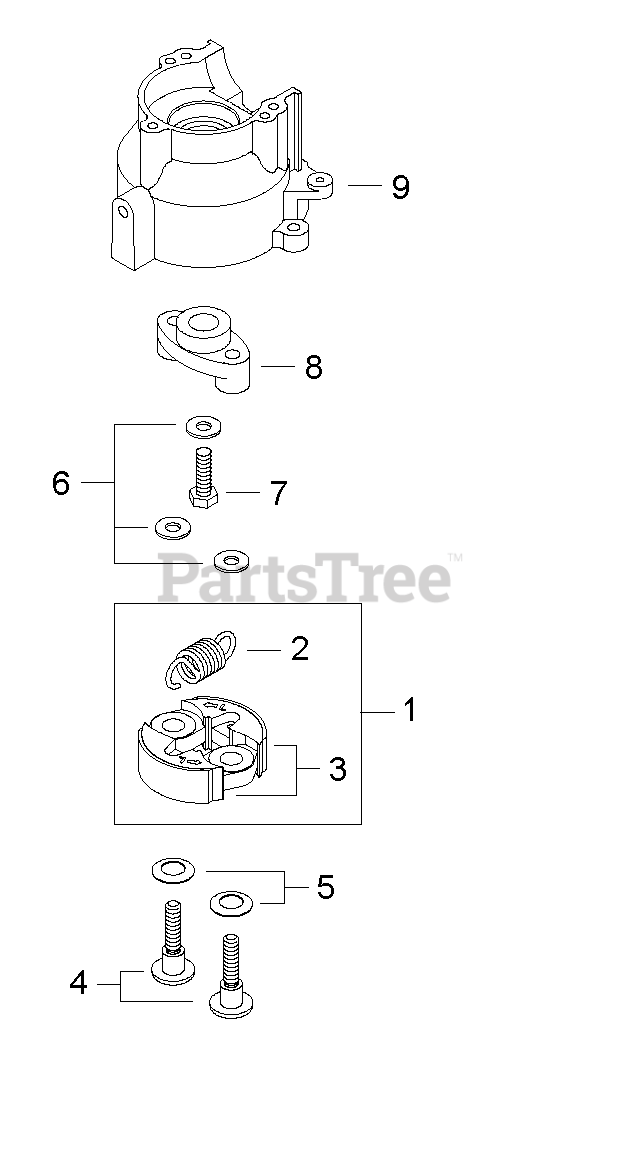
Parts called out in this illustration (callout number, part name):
1	SHOE ASSY, CLUTCH
2	SPRING, CLUTCH
3	SHOE, CLUTCH
4	BOLT, CLUTCH
5	WASHER, SPRING
6	WASHER 6 MM
7	BOLT M6×18
8	BOSS, CLUTCH
9	CRANKCASE ASSY, PTO
